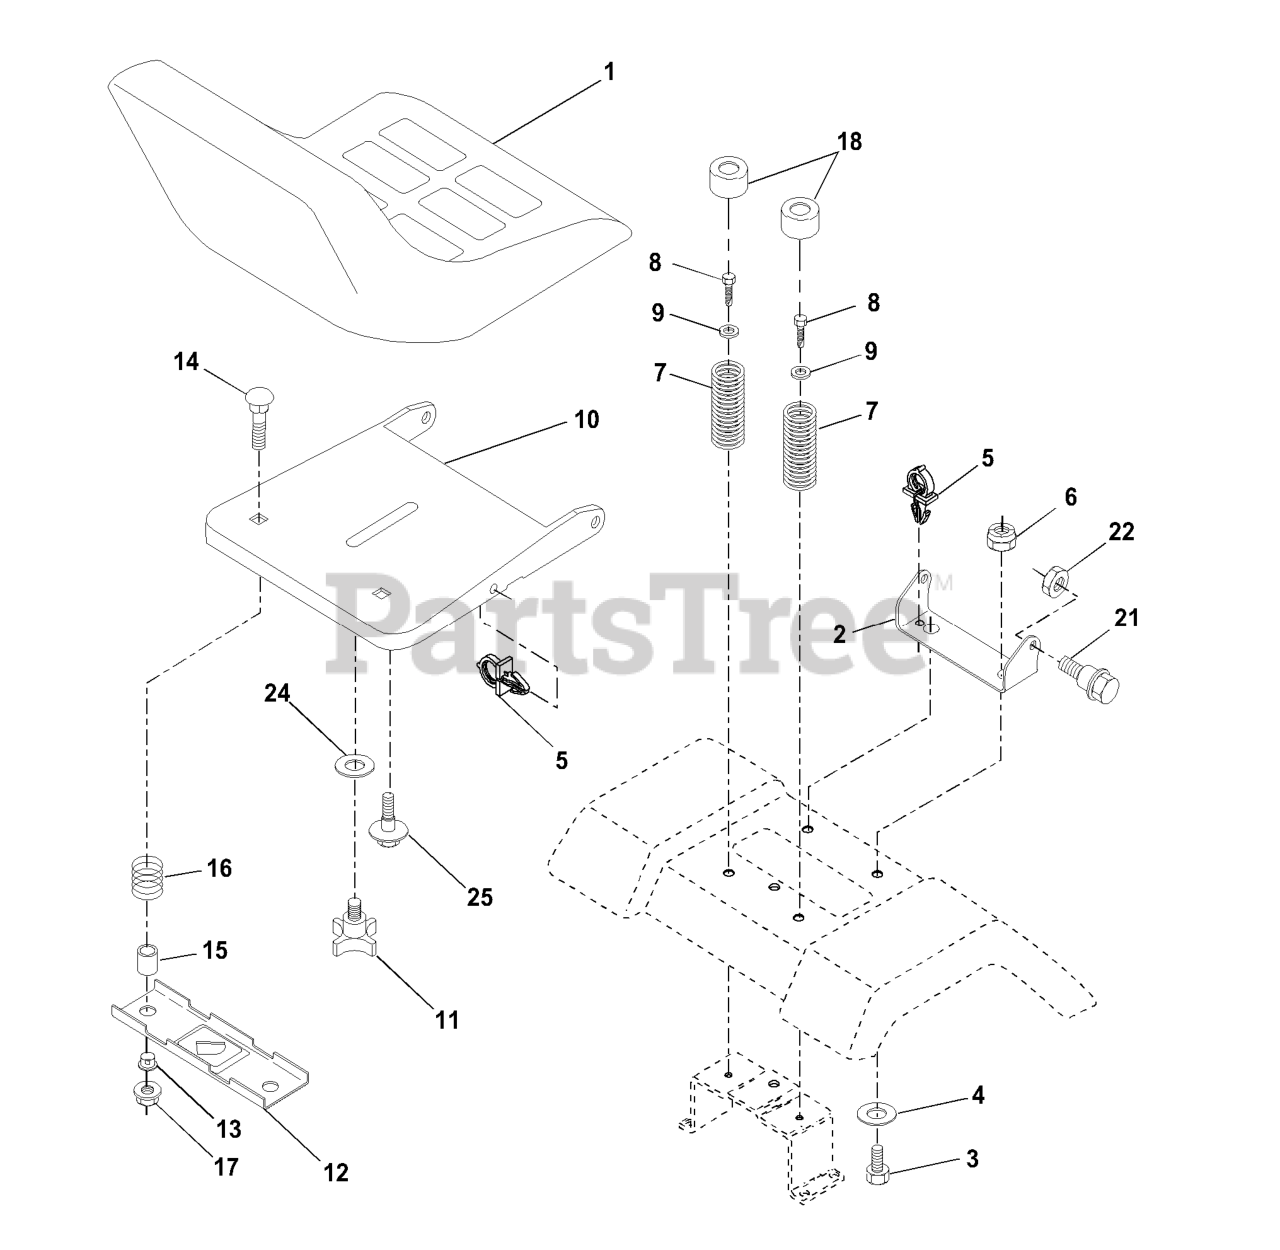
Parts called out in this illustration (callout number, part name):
1	SEAT
2	SEAT PIVOT BRKT
3	BOLT
6	NUT
7	SPRING COMPRESSION
8	SCREW GTV
9	WASHER
10	SEAT PAN
11	KNOB 1/2" YT
12	BRKT SWITCH
14	Bolt Rdhd Sht Nk 1/4-20x1-3/8
15	SPACER SPLIT 28X.96
17	NUT T
18	CAP SPRING
21	BOLT SHOULDER 5/16-18
22	NUT.71038.31-18.HEX.NYLOCK
25	BOLT,SHOULD
